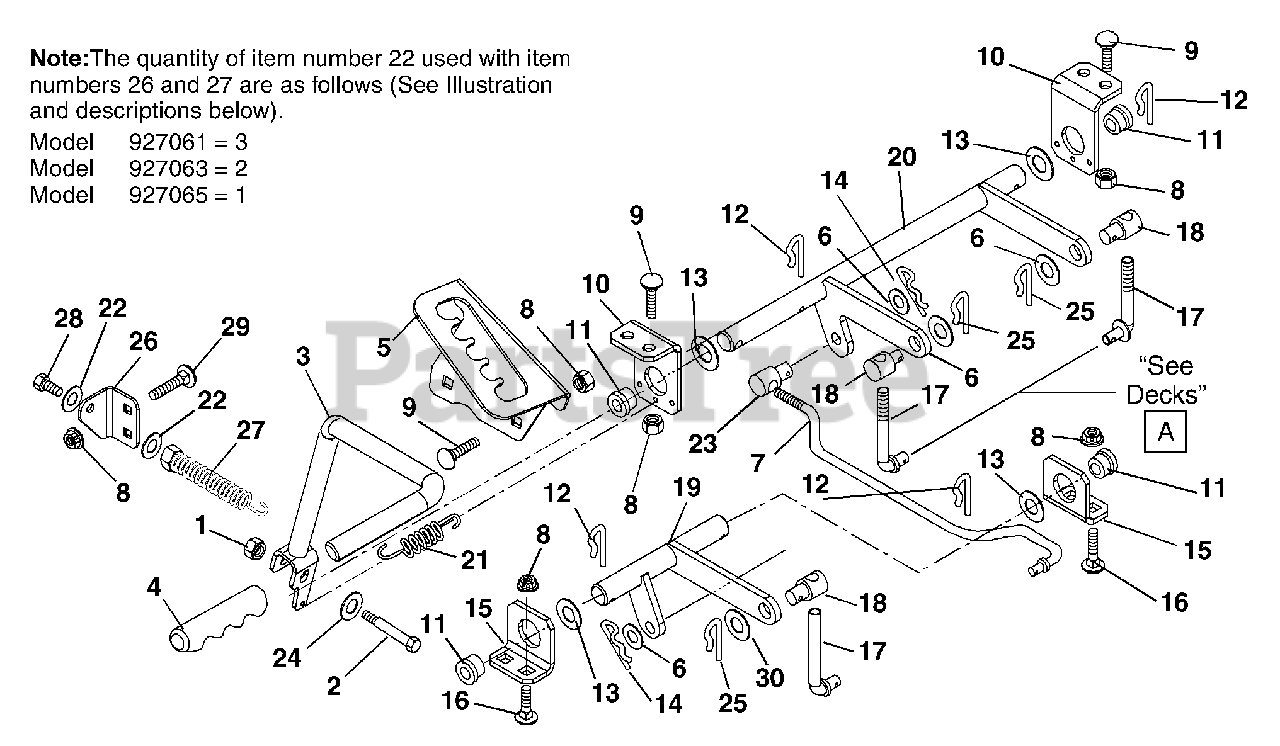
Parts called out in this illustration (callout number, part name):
1	NUT-LK-TOP-FLG .31-18 BLKZC
2	BOLT,SHLDR .38X1.25 .31-18 PLN
3	WLDM'T LIFT HANDLE
5	DETENT PLATE
6	WSHR-FL-STL.511X1.441X.125 YWZ
7	ROD, DECK LIFT
8	NUT-LK-TOP-FLG .38-16 BLKZC
9	BLT-RDHDSQNK .38-16X.75 G5BZ
10	BRACKET-HANGER
11	BSHG-FLG .750X1.000X.625X1.250
12	PIN, SPRING CLIP
13	WSHR-FL-STL .265X1.370X.179
14	PIN, HAIR, EXT - #16 YWZC
15	BRACKET-PIVOT
16	BLT-RDHDSQNK .38-16X1.00 G5BZ
17	LINK, LIFT
18	TRUNNION-.50
19	WMT, FRONT LIFT
20	WMT, REAR LIFT
21	SPRING, EXTENSION
22	WSHR,FLT .438X1.00X.160 ZCC
23	PIVOT, ROD
24	WSHR,FLT .438X1.00X.160 ZCC
25	CLIP, SPRING
26	BKT, SPRING ANCHOR
27	SG-TENS .195X1.147X5.50
28	@BLT-HEX .38-16X1.50 GR5 YWZC
29	BLT-RDHDSQNK .38-16X.75 G5BZ
30	@WSHR-FL-STL.563X1.38X.109YWZC
